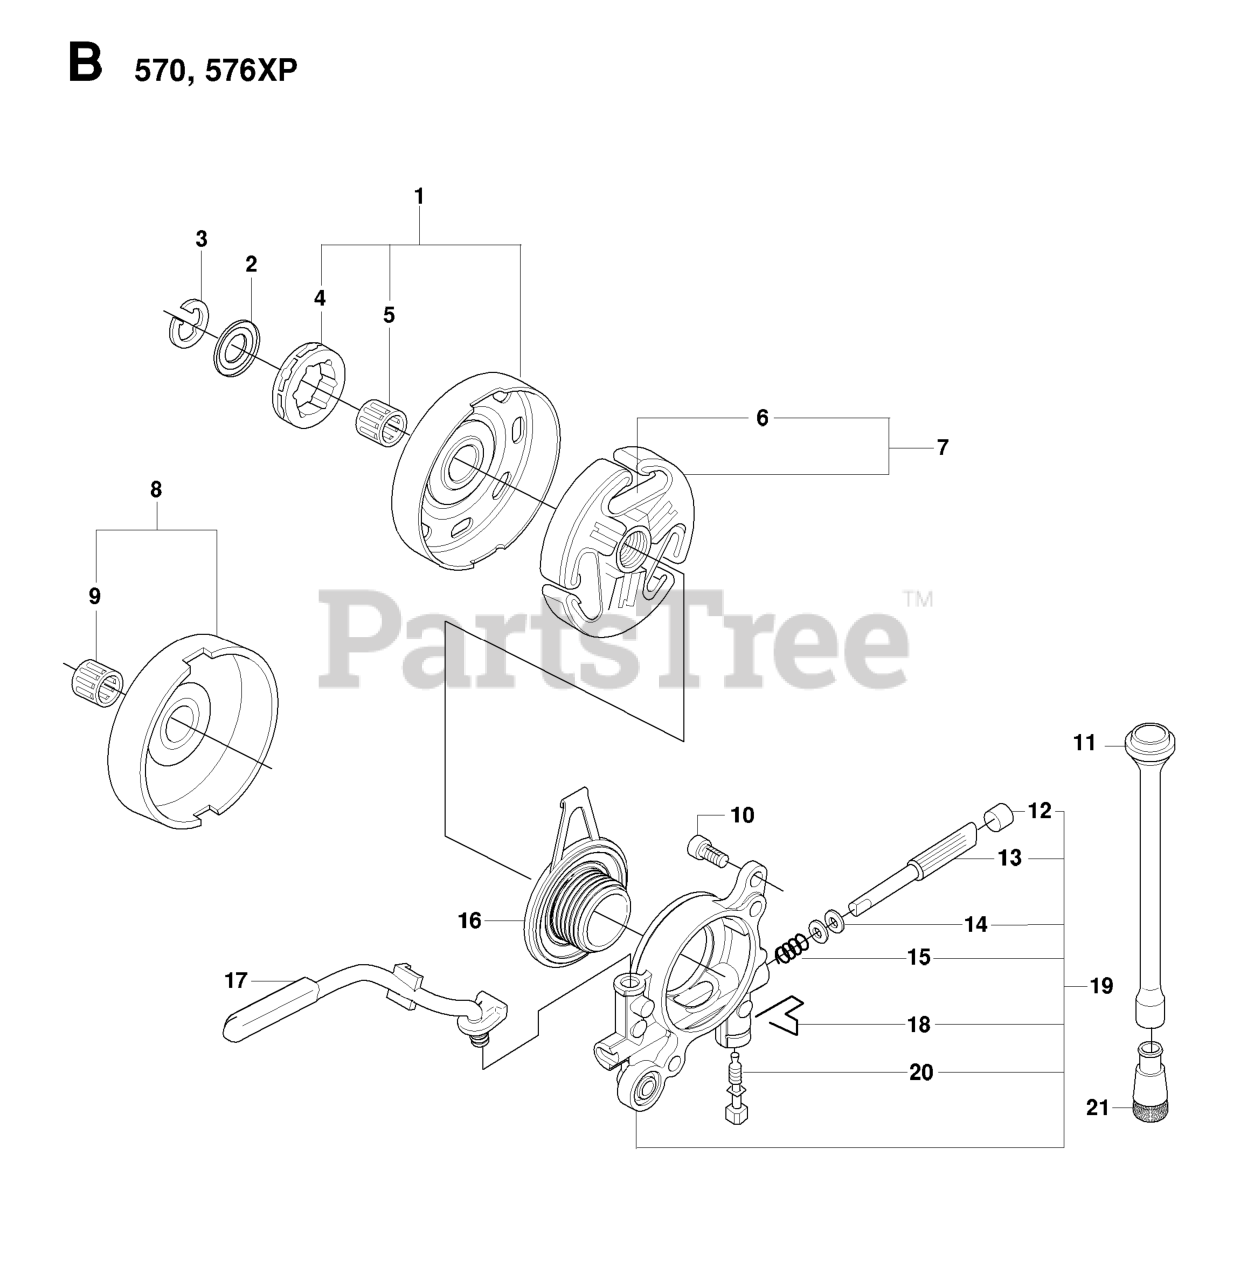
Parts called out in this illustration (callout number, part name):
1	CLUTCH DRUM ASSY
3	RETAINING RING
4	68210 RIMSPROCKET
4	22273 Sprocket 3/8"x8T
5	CLUTCH DRUM BEARING
7	CLUTCH
8	CLUTCH DRUM
9	CLUTCH DRUM BEARING
13	PUMP PISTON
14	WASHER 6.1X9
16	PINION
18	SPRING CLIP
19	OIL PUMP
21	OIL SCREEN
